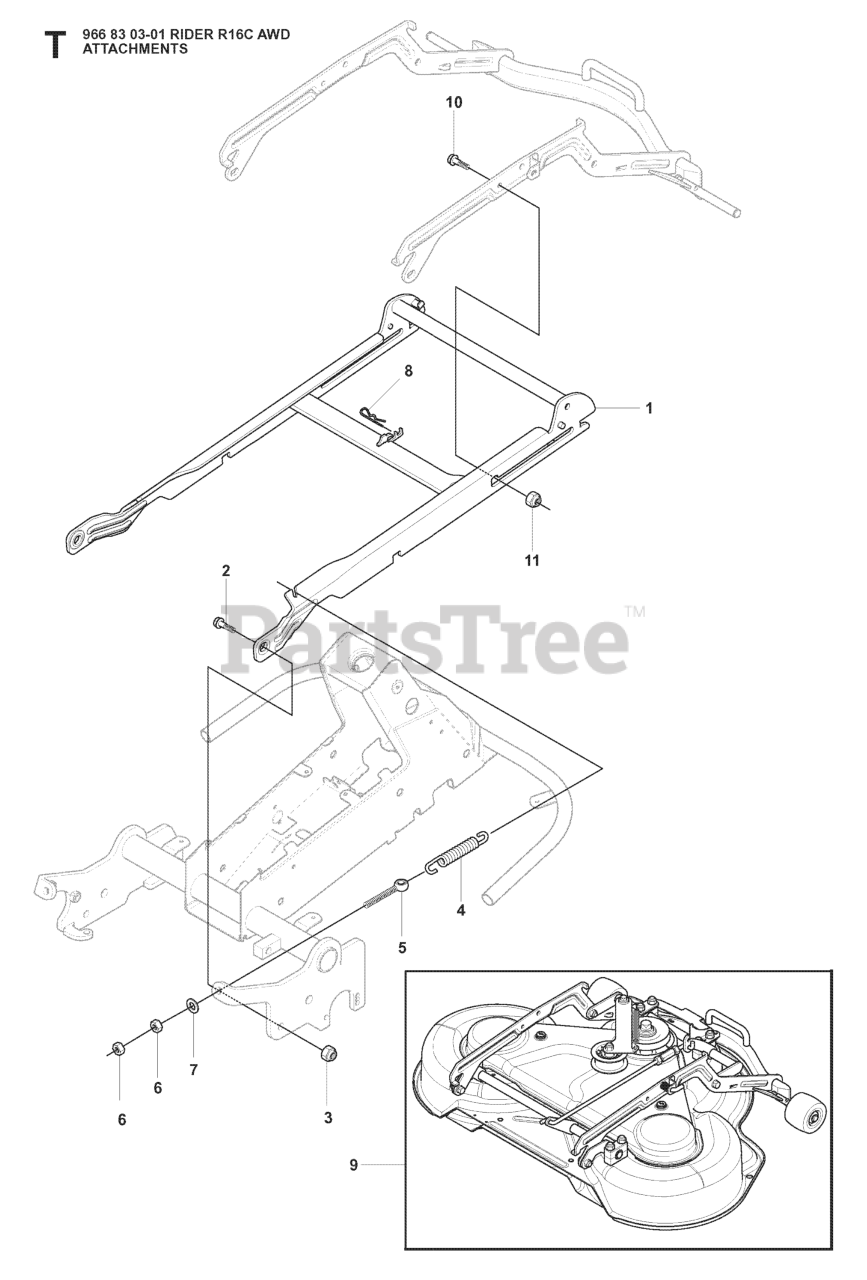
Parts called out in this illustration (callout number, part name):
6	NUT
7	WASHER
10	COLLAR SCREW
11	LOCKNUT M8
